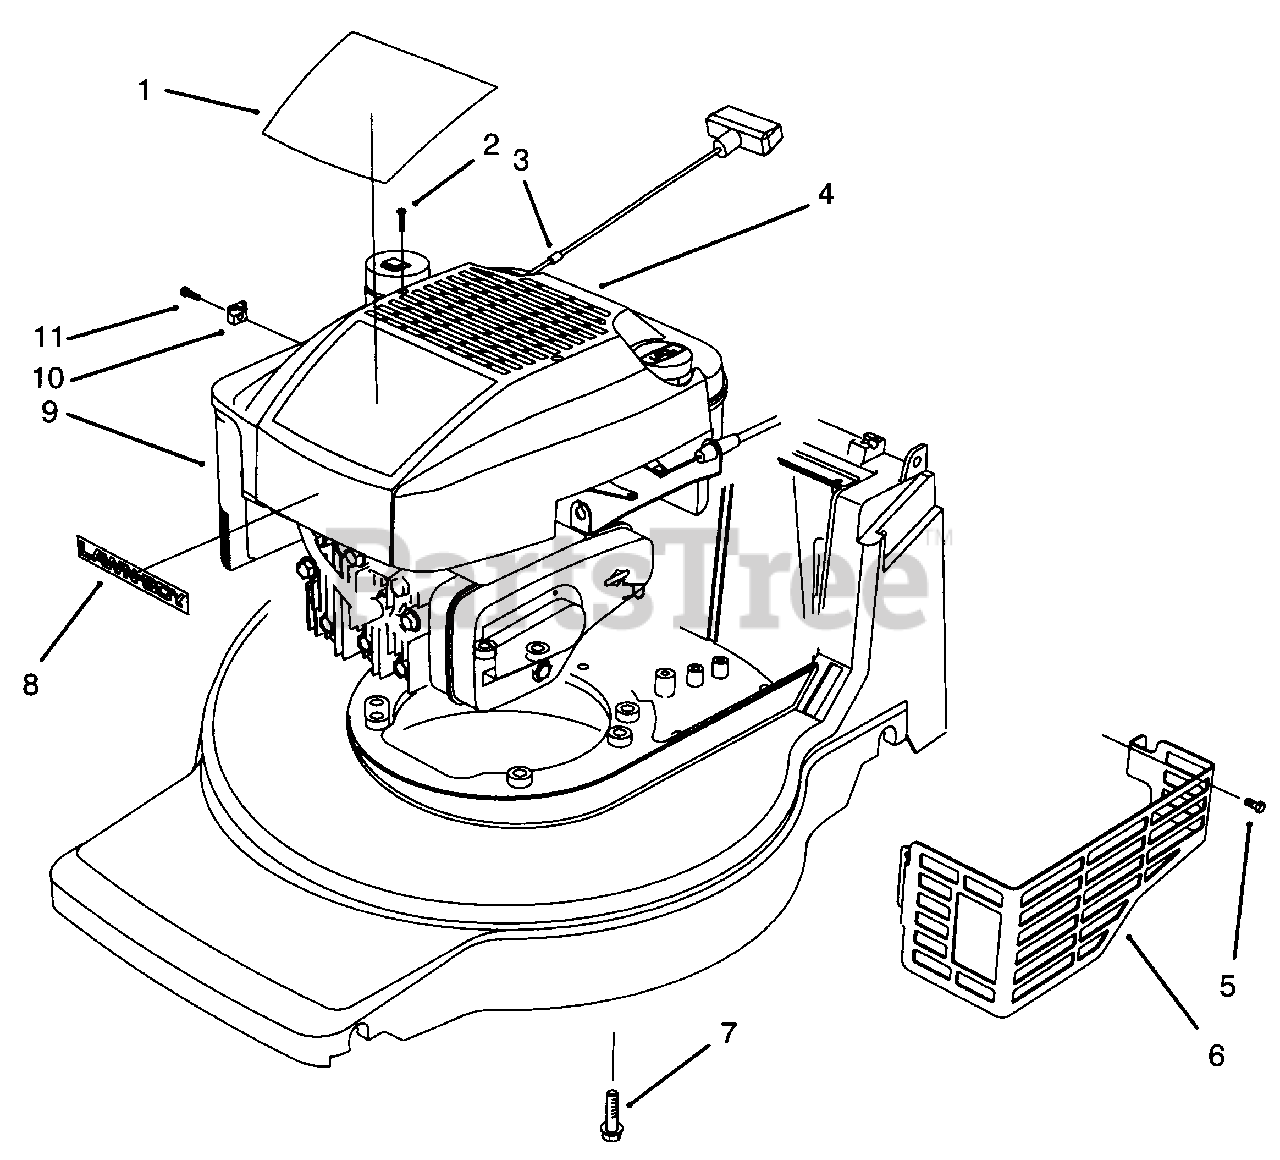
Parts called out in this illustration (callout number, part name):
1	Decal-Recoil
2	Screw-Mounting
3	Stop-Rope
4	Cover-XTE
5	Screw-Hex Washer Head Thread Forming
6	Shield-Muffler
7	Screw-Tapping
8	Decal-Shroud
9	Engine
10	Clamp-Casing
11	Screw-Clamp
